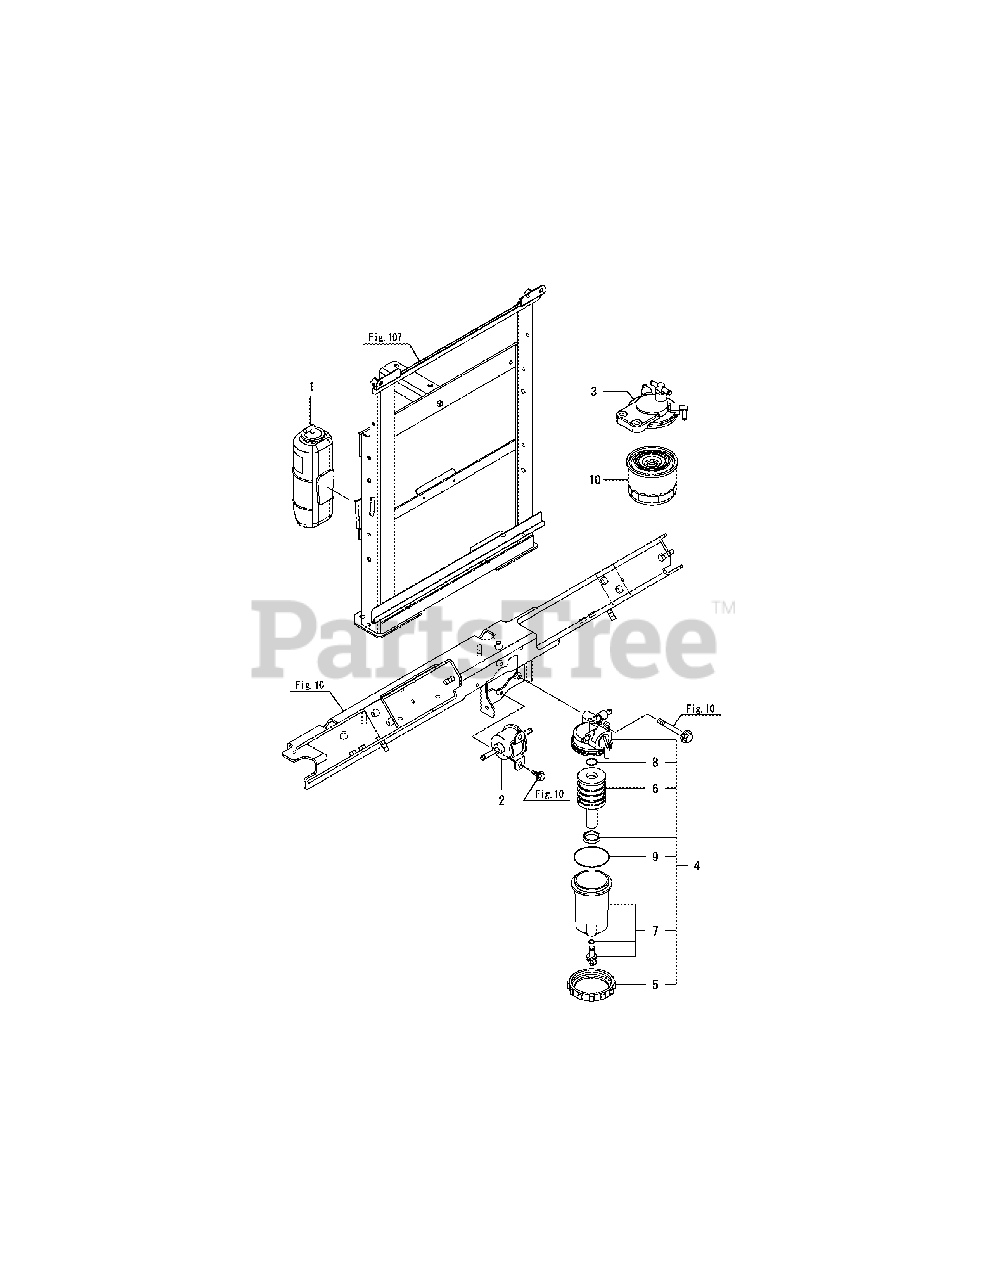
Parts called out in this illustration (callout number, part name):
1	TANK ASSY, SUB
2	PUMP ASSY, FUEL FEED
3	BRACKET, FILTER
4	SEPARATOR ASSY
5	RING, RETAINING
8	O-RING 1A P-16.0
9	O-RING 1A G-65.0
